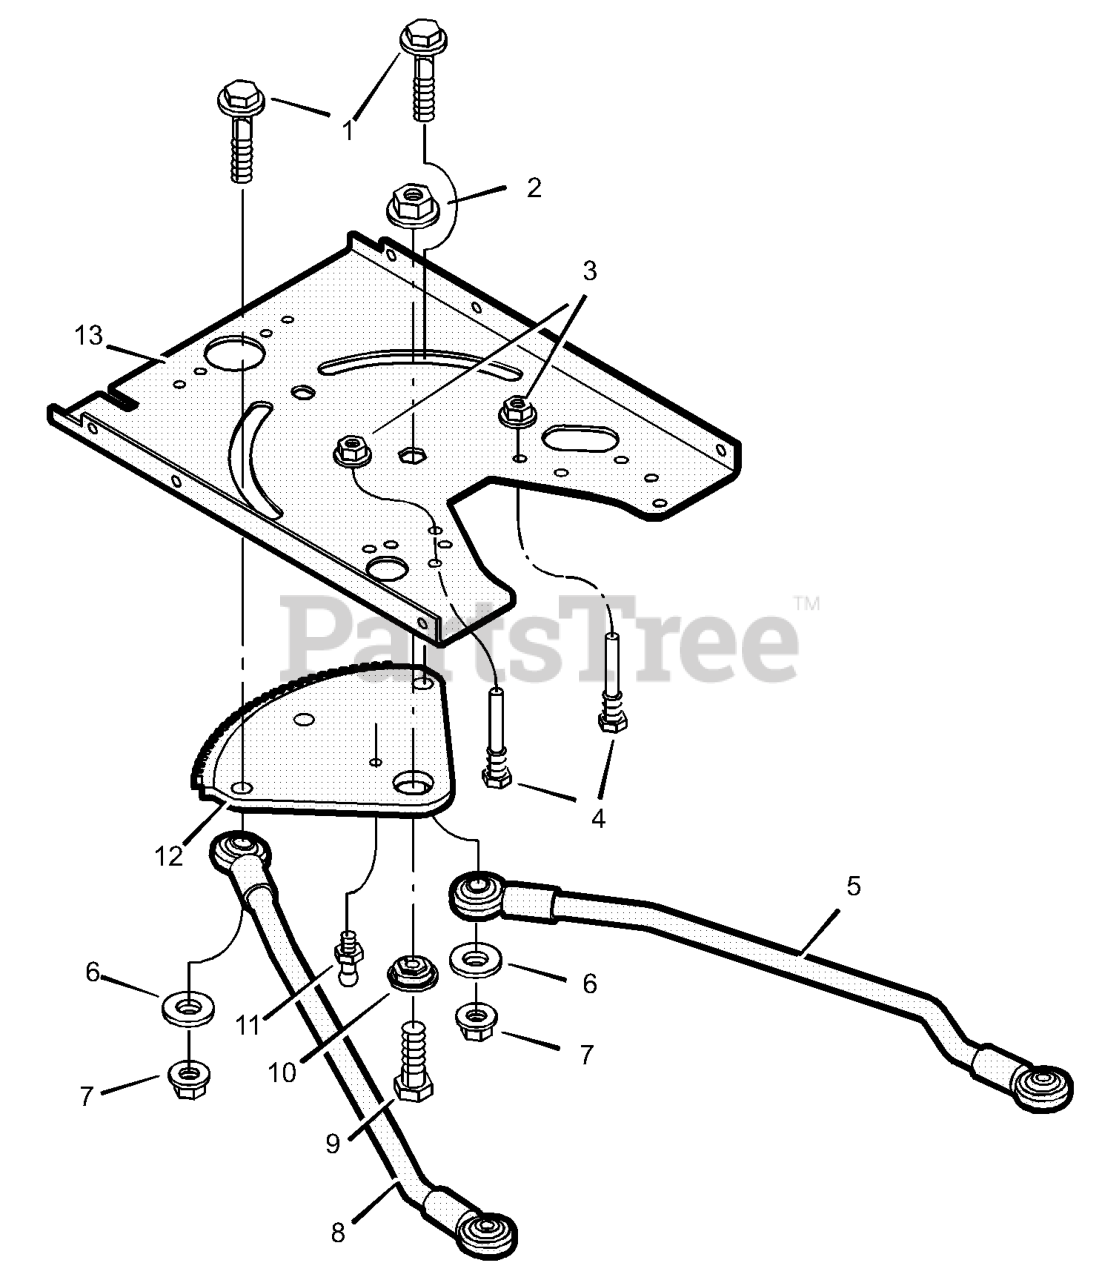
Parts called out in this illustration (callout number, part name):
1	Bolt, Shoulder
2	Nut, Lock
3	Nut, Flange
4	Guide, Screw
5	Link, Left Drag
7	Nut, Flange
8	Link, Right Drag
9	CAPSCREW, Hex Head, 5/16-18 x 1
10	Bearing, Sector Gear
11	Fitting, Lub
12	Gear, Sector
13	Plate, Steering
